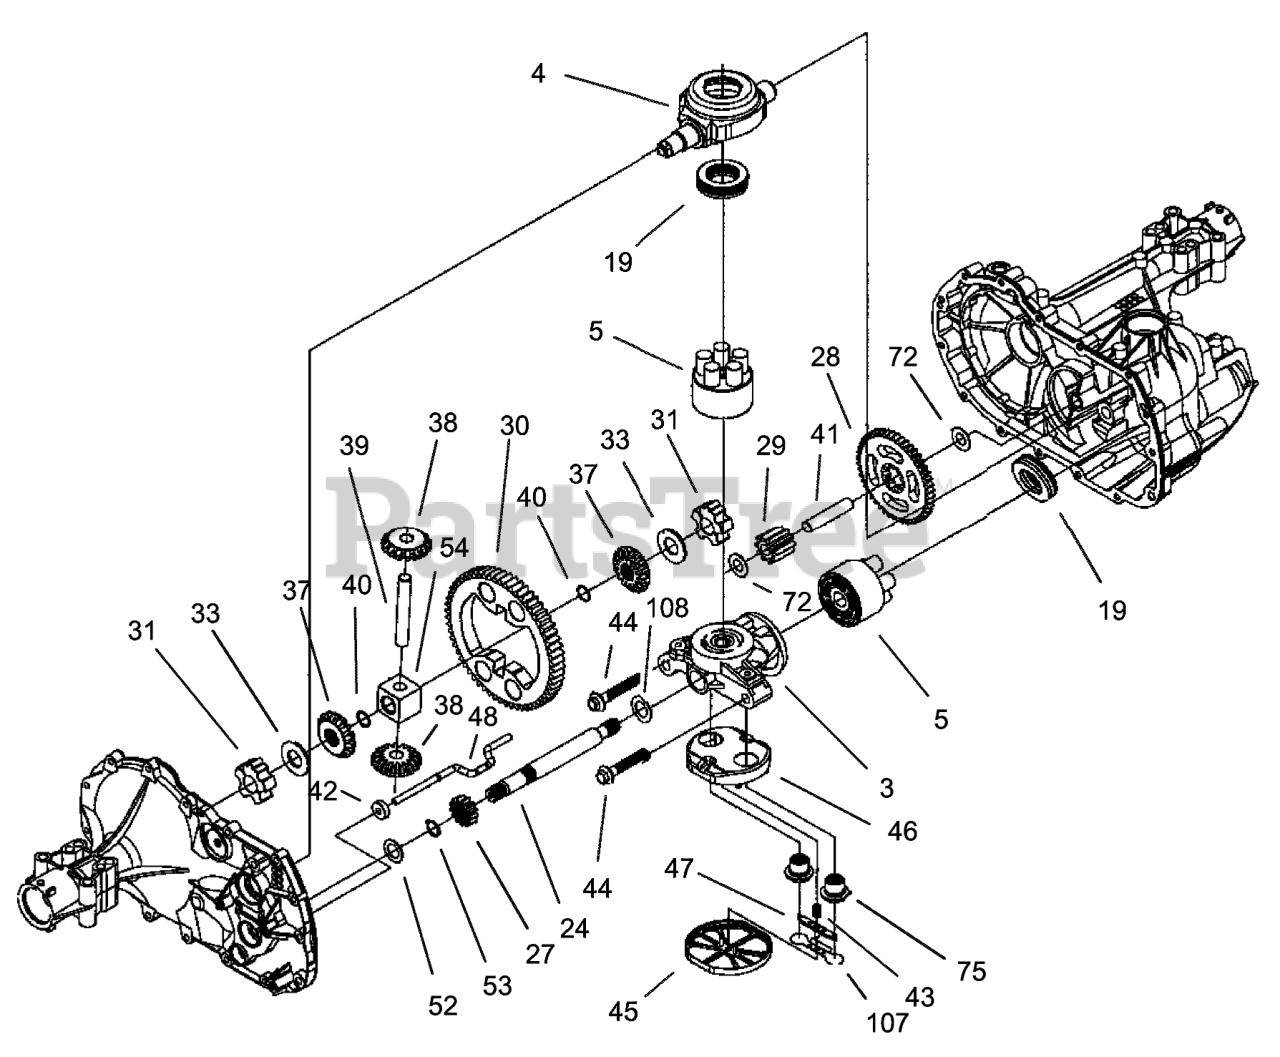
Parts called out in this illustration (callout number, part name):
3	CENTER SECTION ASM
4	SWASHPLATE-TRUNNION
5	CYLINDER BLOCK ASM
19	BEARING-THRUST
24	ARM-CONTROL
27	GEAR-PINNION, 13T
28	GEAR-10T/48T
29	GEAR-JACKSHAFT, 10T
30	GEAR-BULL 60T
31	BEARING-SLEEVE
33	WASHER
37	GEAR-MITER
38	GEAR-MITER 15T
40	RING-RETAINING, SPIRAL
41	PIN-JACKSHAFT
42	MAGNET-RING
43	SPRING-BYPASS
45	FILTER
46	BASE-FILTER
47	ACTUATOR-BYPASS
48	ROD-ACTUATOR, BYPASS
52	WASHER-FLAT
53	RING-RETAINING
54	BEARING-BLOCK, CENTER
72	WASHER
75	CHECK PLUG ASM
107	DEFLECTOR
108	WASHER
